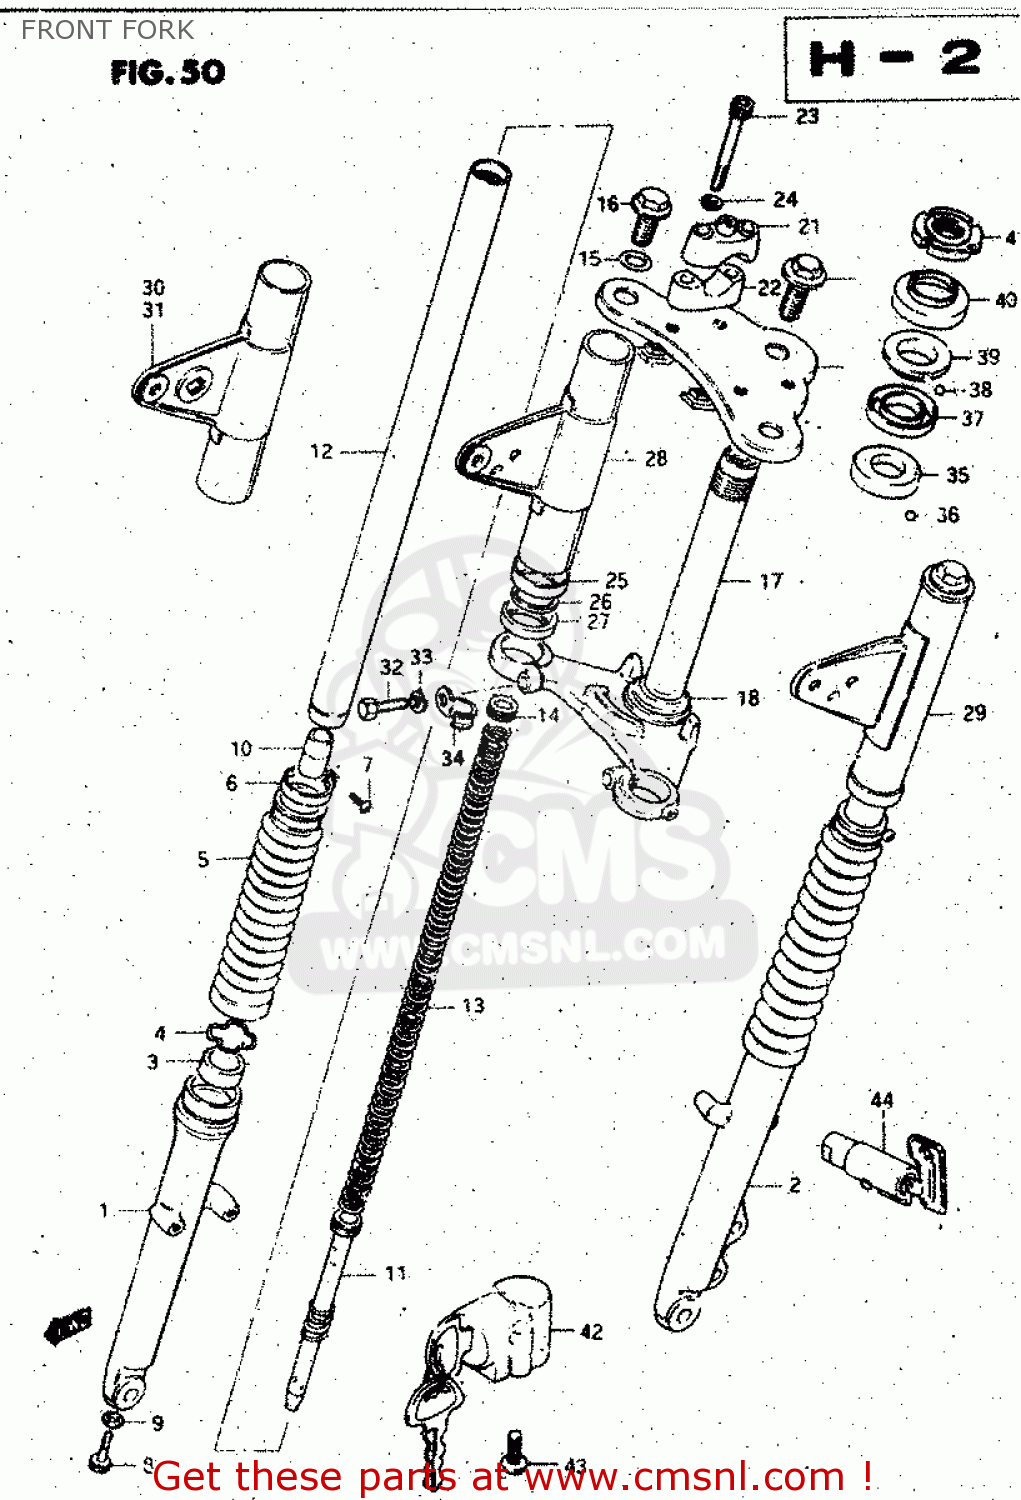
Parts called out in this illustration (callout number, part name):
1	TUBE,OUTER,R
2	TUBE,OUTER,L
3	OIL SEAL,FRONT FORK
4	RING,SNAP
5	BOOT
6	BAND,BOOT
7	SCREW
8	BOLT
9	GASKET (NAS)
10	PIECE,OIL LOCK
11	FRONT FORK DAMPER TUBE
12	TUBE, INNER
13	SPRING
14	NUT
15	O RING
16	CAP
17	STEM,STEERING
18	RACE,STEERING OUTER LWR
19	HEAD,STEERING STEM
20	BOLT
21	HOLDER,HANDLEBAR(BLACK)
22	HOLDER,HANDLE UPR
23	BOLT
24	LOCK WASHER
25	CUSHION,HEAD LAMP BRACKET
26	GUIDE,BRACKET
27	SPACER
28	BRACKET,HEADLAMP,R
29	BRACKET,HEADLAMP,L
30	BRACKET,HEADLAMP,R
31	BRACKET,HEADLAMP,L
32	BOLT,FR FORK LWR(12X33)
33	WASHER,LOCK
34	CLIP
35	LACE,STEERING INNER LWR
36	BALL
37	RACE,STEERING INNER UPR
38	BALL
39	RACE,STEERING OUTER UPR
40	DUST SEAL,STEERING UPR
41	NUT,STEERING STEM(25X44X10)
42	LOCK ASSY,STEERING
43	SCREW
44	LOCK ASSY,STEERING(NEIMAN)
